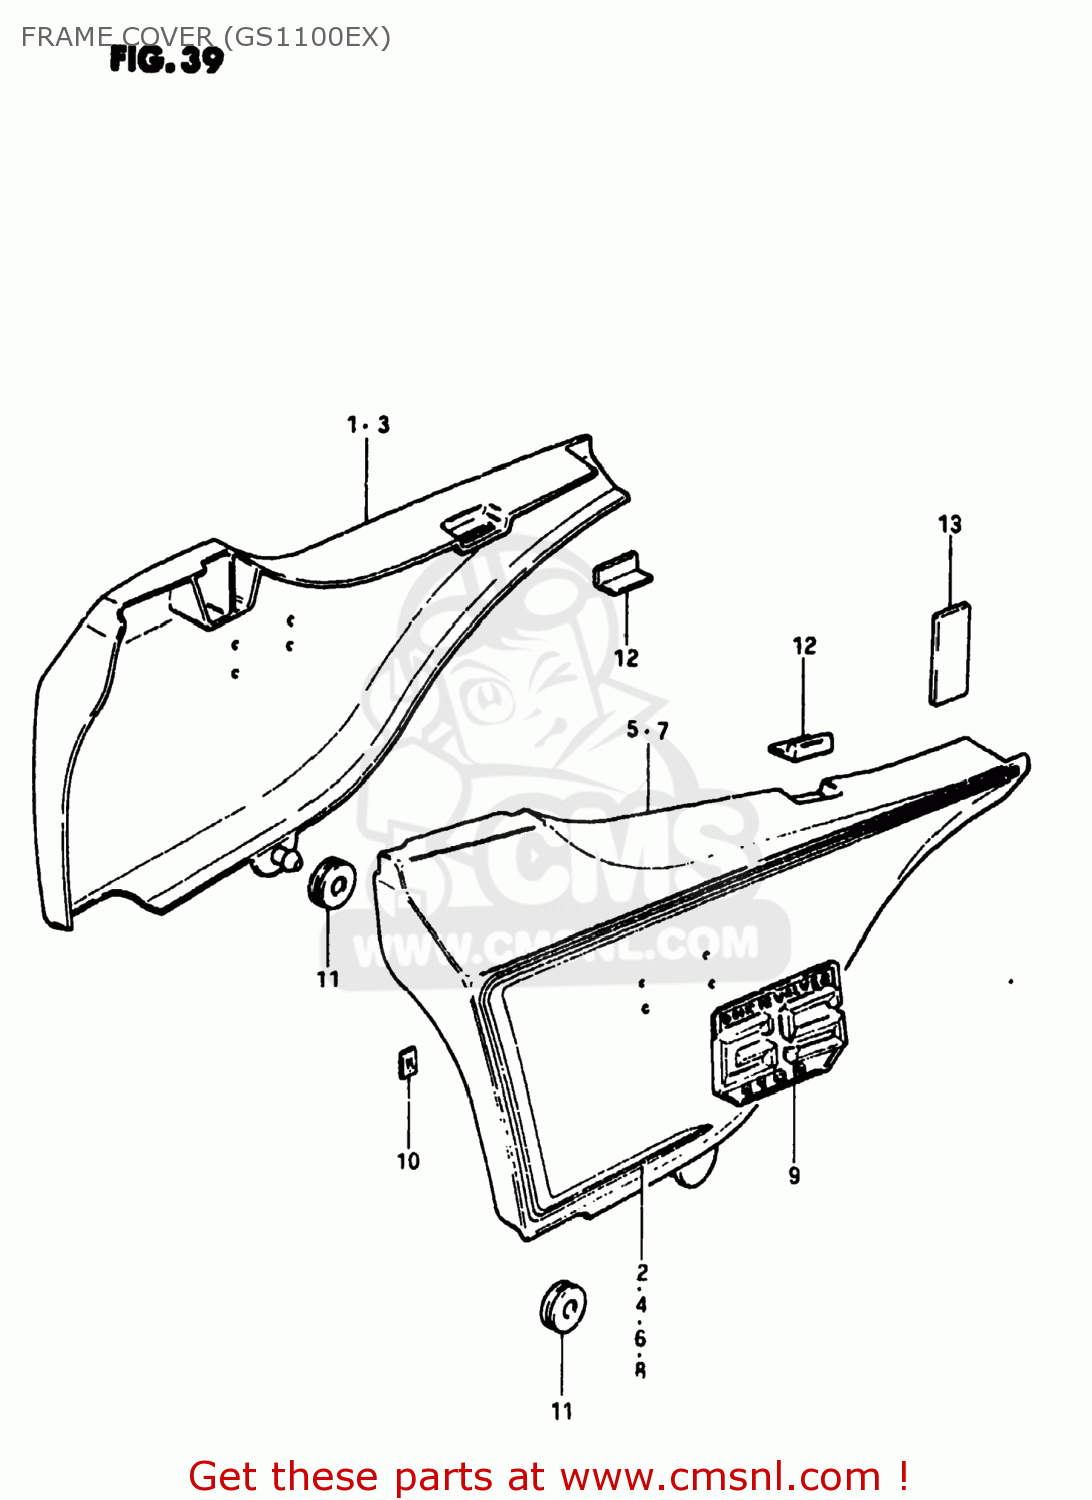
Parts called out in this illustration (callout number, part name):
1	COVER,FRAME,R
3	COVER,FRAME,R
5	COVER,FRAME,L
7	COVER,FRAME,L
9	EMBLEM,FRAME COVER
10	NUT
11	CUSHION
12	CUSHION,FRAME COVER
13	RUBBER,FRAME COVER
